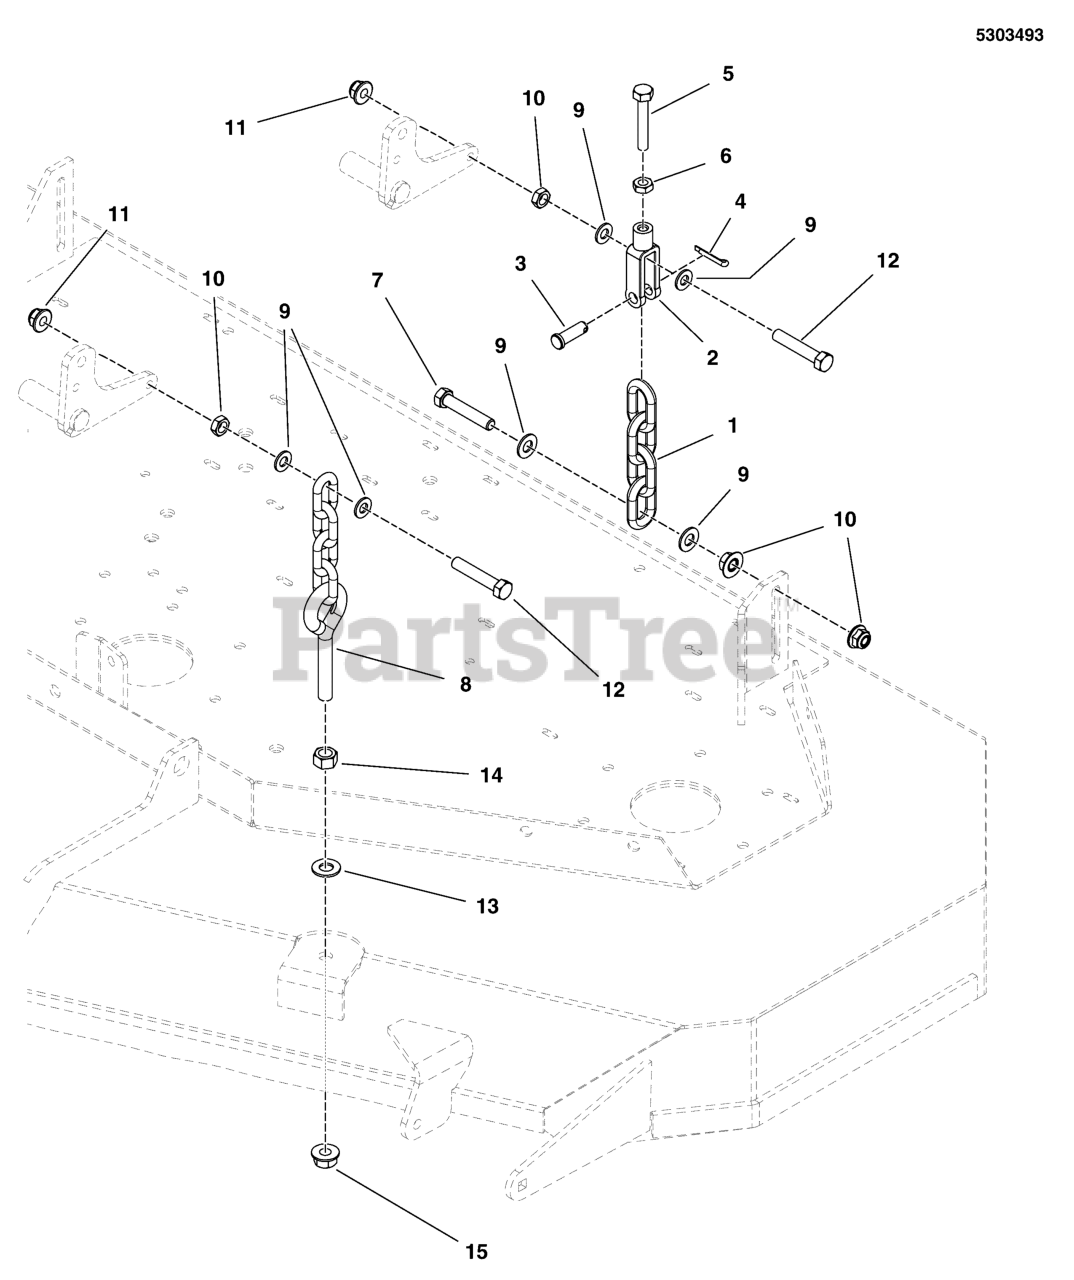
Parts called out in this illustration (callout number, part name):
1	CHAIN, 5/16" GD30, 4 LINKS
2	CLEVIS, 5/16-18, 3/8 PIN HOLE, CLR ZINC
3	PIN, CLEVIS, 3/8 X 1-1/8, PLATED
4	PIN, COTTER, 1/8 X 3/4
5	BOLT, 5/16-18 X 2 GD5 TFL
6	NUT, 5/16-18 HEX JAM
7	BOLT, 3/8-16 X 1-3/4" GD5 CZ
8	HANGER, FRONT DECK - 4 LINK, 5.5" EB
9	WASHER, 3/8 SAE
10	NUT, 3/8-16 HEX SERRATED FLANGE
11	NUT, 3/8-16 HEX SIDE LOCK
12	BOLT, 3/8-16 X 2, GD5, CZ
13	WASHER, 1/2 SAE
14	NUT, 1/2-13 HEX, YZ
15	NUT, Hex Flange, Nylock, 1/2-13
